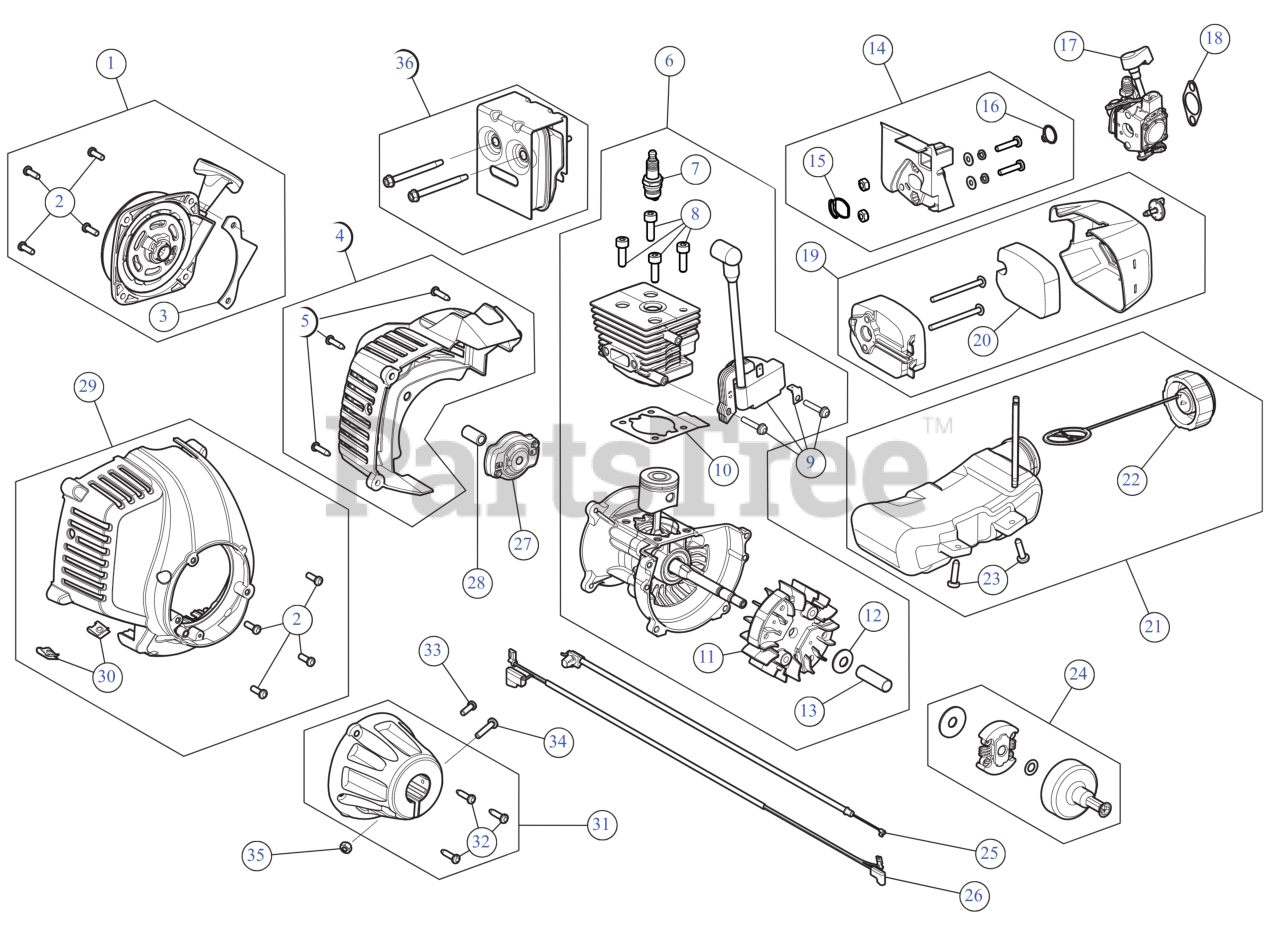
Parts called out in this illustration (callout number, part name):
1	STARTER ASSEMBLY RR
2	SCREW:10-32X.562:#8P
3	STARTER GUARD
4	ENGINE COVER ASSEMBLY RR
5	SCREW, #8-16X.750 PH
6	SHORT BLOCK
7	SPARK PLUG
8	SCREW 1/4 x 20 x .8125
9	MODULE 27CC DIG
10	GASKET CYL
11	FLYWHEEL ASSEMBLY 27CC
12	BELL WASHER
13	SPACER
14	INTAKE ASSEMBLY
15	O-RING
16	O-RING
17	CARBURETOR (WALBRO)
18	GASKET CARB
19	AIRCLEANER ASSEMBLY
20	AIR FILTER
21	FUEL TANK ASSEMBLY
22	FUEL CAP ASSEMBLY
23	SCREW:10-6 x .75
24	SMALL CLUTCH ASSEMBLY W/SMALL DRUM
25	THROTTLE CABLE
26	LEAD WIRES
27	PAWL ASSEMBLY AC5
28	ELECTRIC START ADP
29	ENGINE COVER
30	NUT, TINNERMAN U-T
31	CLUTCH COVER ASSEMBLY
32	SCREW, #8-16X.750 PH
33	SCREW, 8-32 x .312 P
34	SCREW
35	HEX NUT
36	MUFFLER ASSEMBLY
